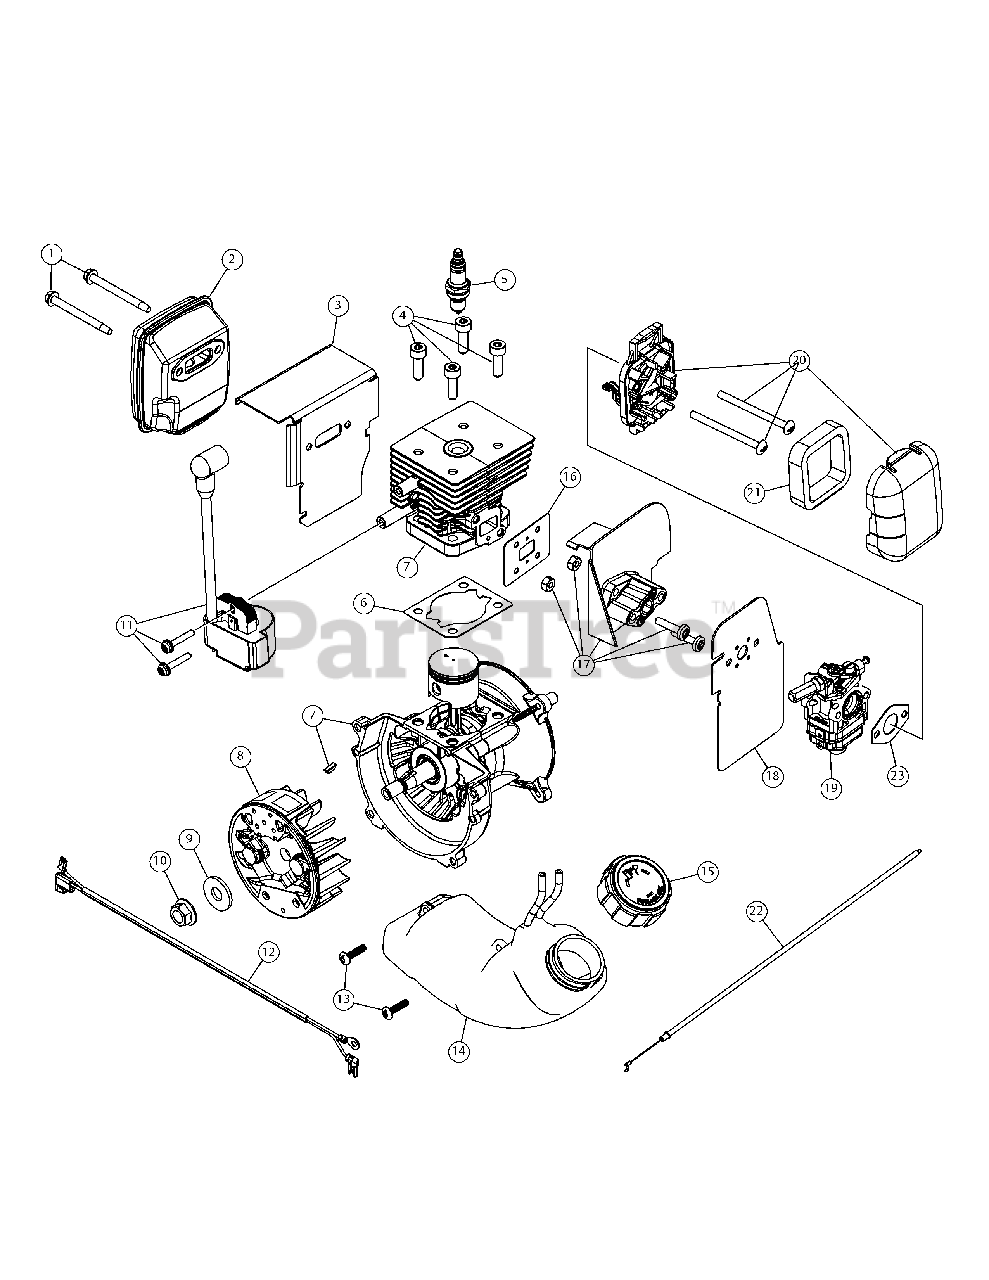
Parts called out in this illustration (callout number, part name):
1	Muffler Screw
2	Muffler Assembly (Incl. 1 & 3)
3	Muffler Gasket
5	Spark Plug
6	Cylinder Gasket
7	Shortblock Assembly (Incl. 4 - 6 & 8)
8	Flywheel Assembly
11	Module Assembly
14	Fuel Tank Assembly (Incl. 13 & 15)
16	Insulator Gasket
17	Insulator Assembly (Incl. 16)
18	Carburetor Gasket
19	Carburetor Assembly (Incl. 20)
20	Air Cleaner Assembly (Incl. 21)
22	Throttle Cable
23	Carburetor Gasket
